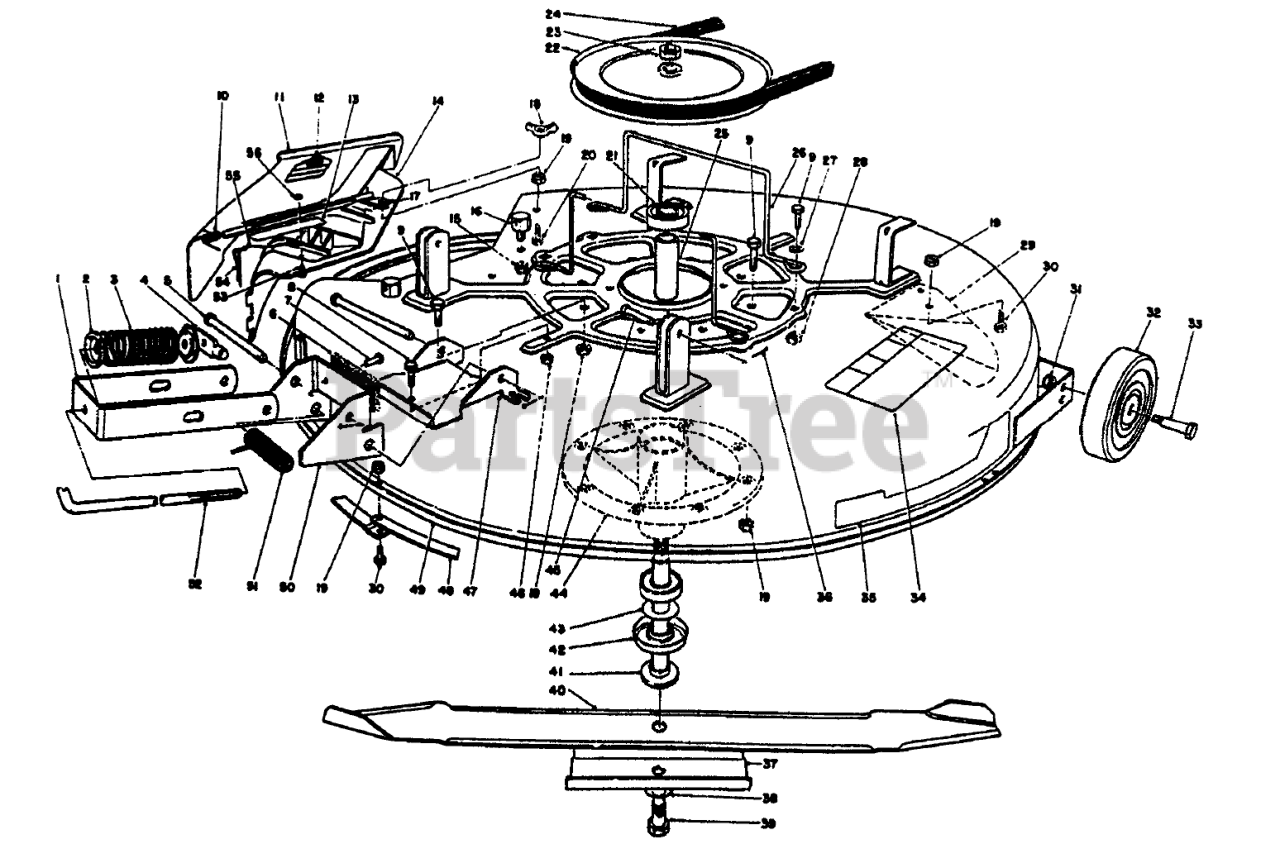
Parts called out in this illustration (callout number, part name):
1	Bracket-Engagement
2	RETAINER-SPR. TOP
3	SPRING-COMPRESSION
4	SHAFT-DECK ADJ.
5	PIN-CLEVIS
6	PAD-BRAKE
7	RIVET .187 X 7/16 BRASS
8	SCREW-HH
9	SCREW-HH
10	SPRING
11	Deflector (Incl. Ref. #12)
12	DECAL-DANGER
13	DECAL-DANGER, DEFLECTOR
14	Assy.-Cover, Discharge (Incl. Ref. #53-56)
15	NUT-LOCK, SIDE
16	POST-PIVOT
17	Brace-Cover, Rear
18	NUT-WING
19	NUT-LOCK, NI
20	SCREW-HH
21	BEARING-BALL
22	PULLEY
23	NUT-HEX
24	V-BELT, DECK
25	SPACER-BEARING
26	GUIDE-BELT
27	WASHER-PLAIN
28	NUT-RETAINER
29	Kicker
30	SCREW-HH
31	NUT-LOCK, NI
32	WHEEL-DECK
33	BOLT-WHEEL
34	DECAL-DANGER, THROWN OBJECT
35	DECAL/RECYCLER 32" BACK
36	PIN-COTTER
37	STIFFENER
38	Washer-Belleville
39	SCREW-HH
40	BLADE-RECYCLER
41	SHAFT-SPINDLE
42	SHIELD-BEARING
43	SPACER-HARDNED
44	SPINDLE
45	PIN-CLEVIS
46	NUT-HEX
47	Plate-Deck, Brake Mtg.
48	RING-DECK
49	Deck-Cutting
50	Brake (Incl. Ref. #6-7)
51	SPRING
52	ROD-ENGAGEMENT
53	RIVET-BLIND
54	PIN-LOCKING, CHUTE
55	LANYARD
56	WASHER-PLAIN
